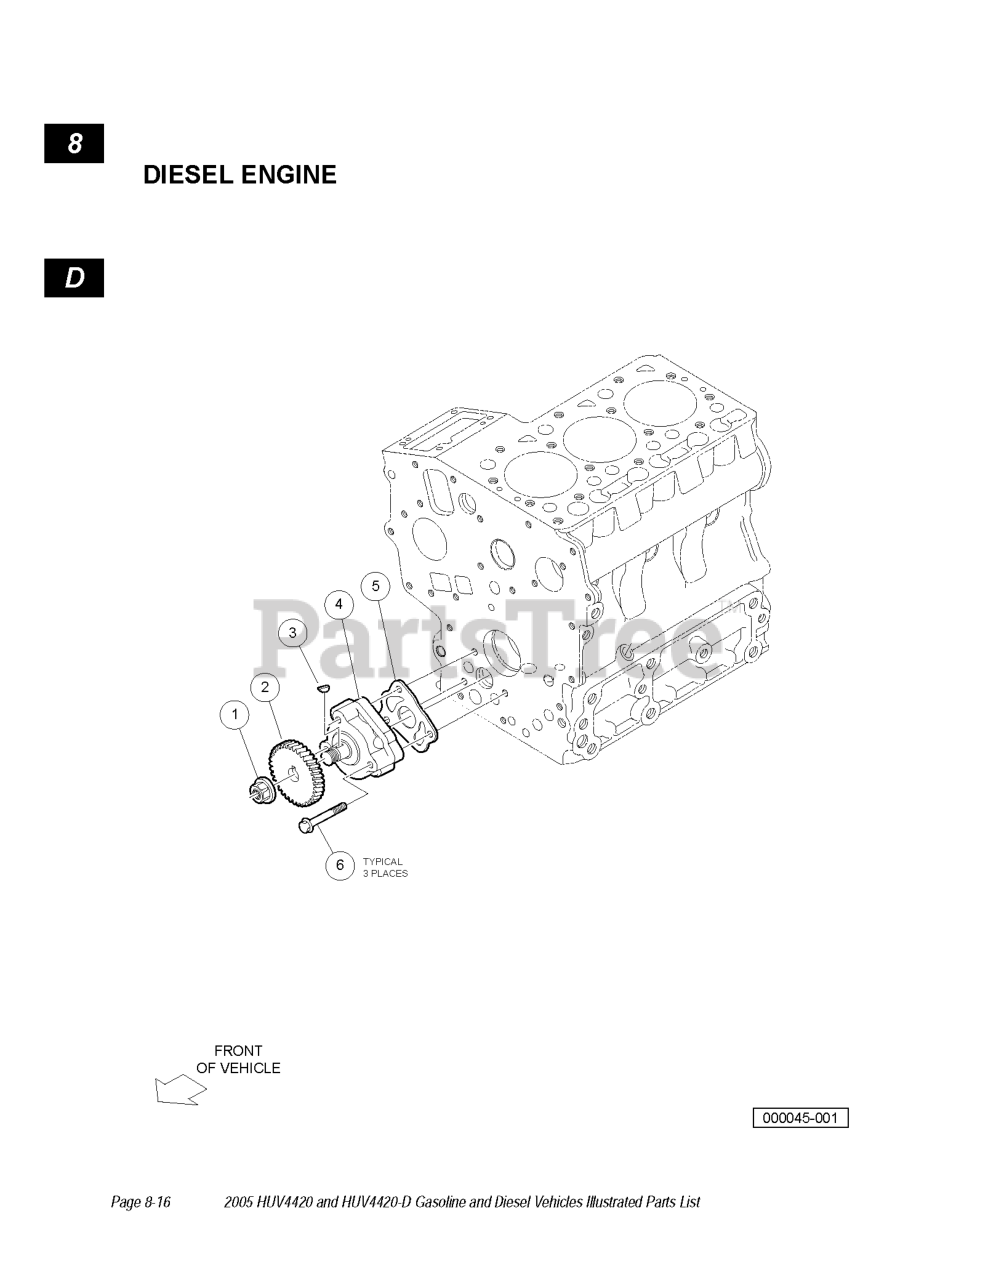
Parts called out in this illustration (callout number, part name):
1	WASHER, SPRING, M6
2	GEAR, OIL PUMP DRIVE
3	KEY, FEATHER, 8X4
4	ASSY, PUMP, OIL
5	GASKET, OIL PUMP NA
6	BOLT, OIL PUMP
